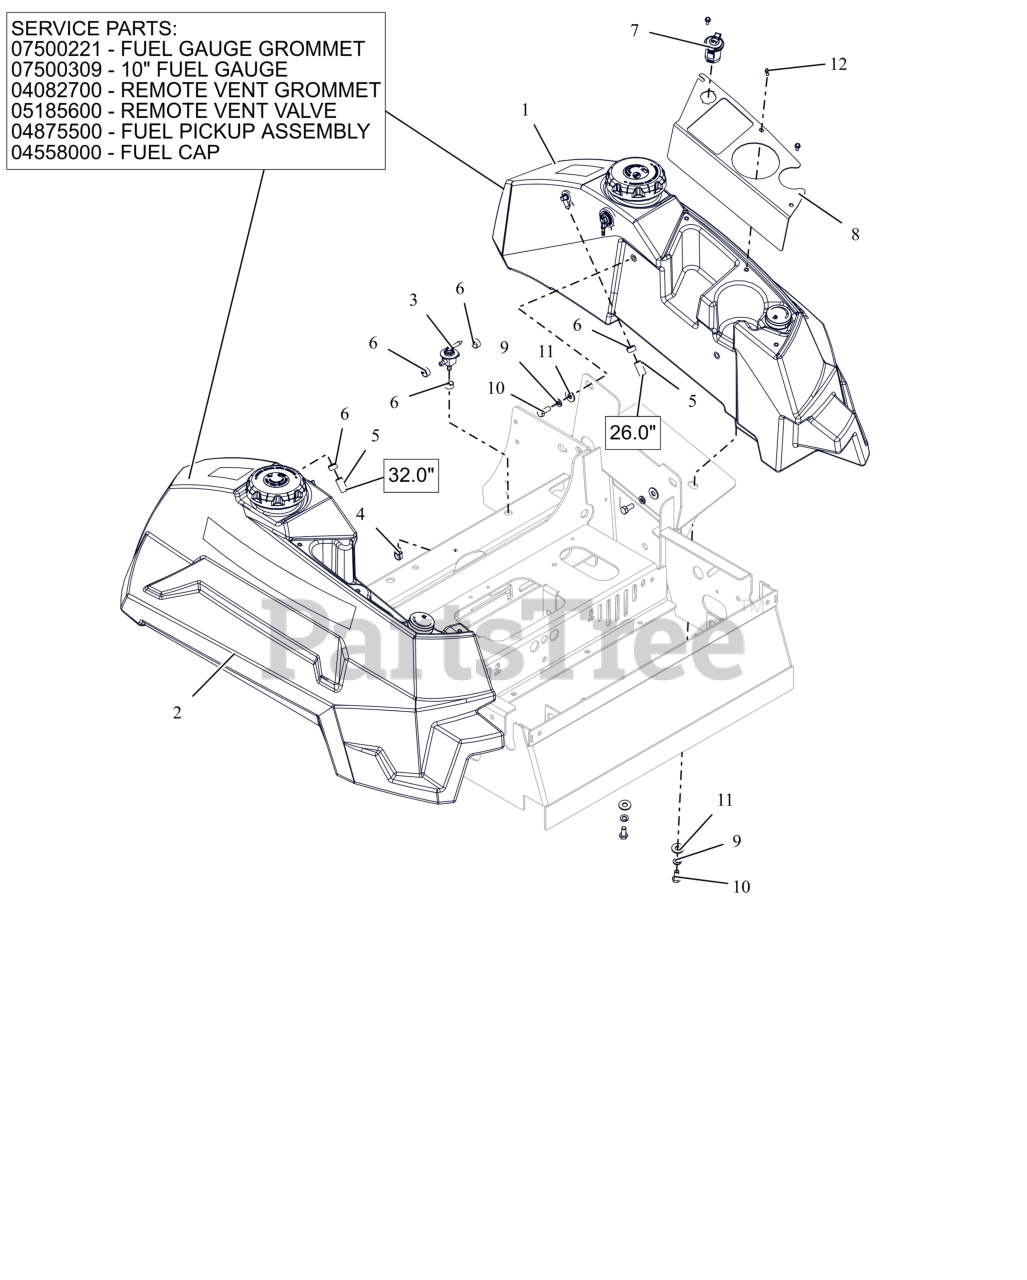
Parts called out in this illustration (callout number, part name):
1	ASM, LH FUEL TANK
1	GROMMET, FUEL GAUGE
1	GAUGE, REMOTE FUEL SEALED 10"
1	GROMMET, REMOTE VENT NITRILE
1	VALVE, COMBINATION VENT 3/16
1	ASSM,LRG TANK FUEL PICKUP LINE
1	CAP, FUEL VENTIN AUTOLOCK
2	ASSY-RH, PT400 FUEL TANK
2	GROMMET, FUEL GAUGE
2	GAUGE, REMOTE FUEL SEALED 10"
2	GROMMET, REMOTE VENT NITRILE
2	VALVE, COMBINATION VENT 3/16
2	ASSM,LRG TANK FUEL PICKUP LINE
2	CAP, FUEL VENTIN AUTOLOCK
3	VALVE - FUEL
4	ROUTING CLIP (1/2" ID)
5	HOSE, .25 LOW-PERM BULK GAS
6	CLAMP, FUEL LINE
7	PORT, 12 VOLT POWER
8	CUP HOLDER/POCKET PLATE - RED
9	WSHR,LK-REG .312X.078 ZCC
10	BLT,HEX .31-18X.75 G5 ZCC
11	WSHR,FLT .375X.875X.083 ZCC
12	SCR-MCH 10-24X.38 HWHSTAINLESS
